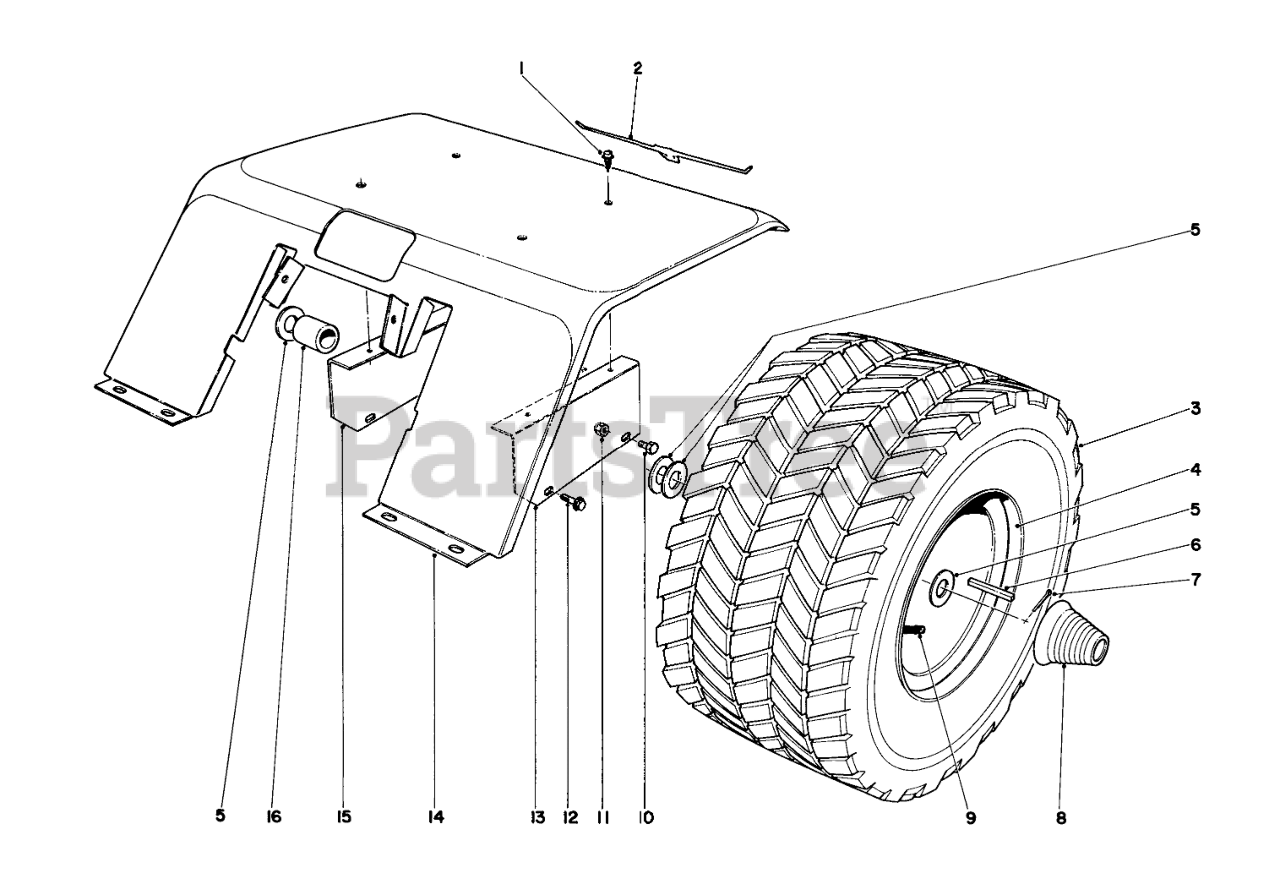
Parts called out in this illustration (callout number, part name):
1	10-16 X 3/8 THDG SCREW
2	Decal
5	Washer
6	KEY-CLUTCH
7	PIN-COTTER
8	Hub Cap
9	VALVE -STEM
10	SCREW-HH
11	NUT-LOCK, CONE
12	1/4-20X5/8 THDG SEMS
13	Fender Support R.H.
14	Fender
15	Fender Support L.H.
16	Spacer
